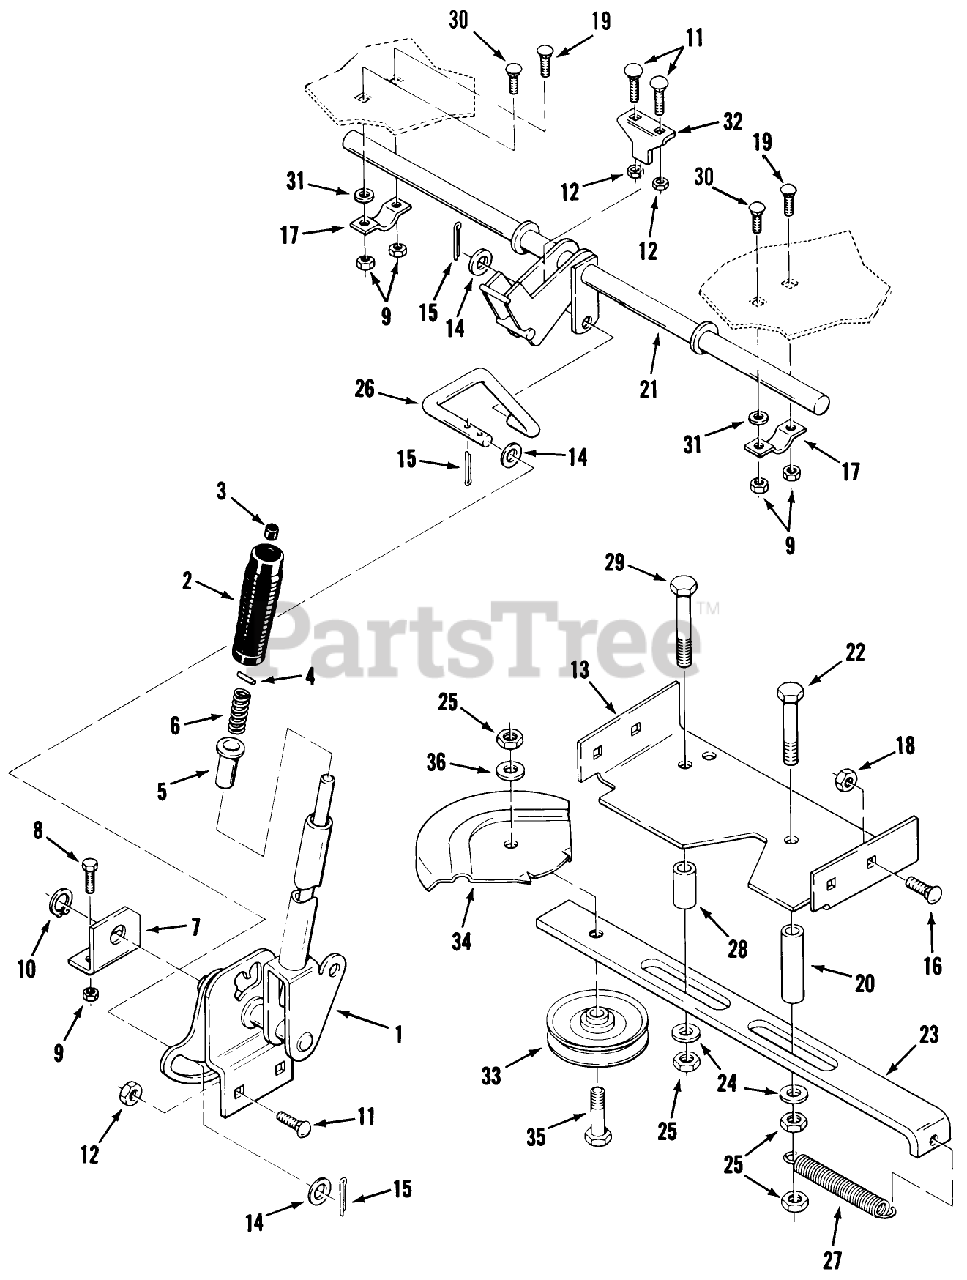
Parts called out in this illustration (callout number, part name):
2	HANDGRIP
3	CAP-ROD, PLUNGER
4	PIN-SPIROL
5	RETAINER-SPRING
6	SPRING-COMPRESSION
13	ASS'Y-FRAME BRACE *R
17	CLAMP
27	SPRING-EXTENSION
34	GUARD-IDLER PULLE *R
